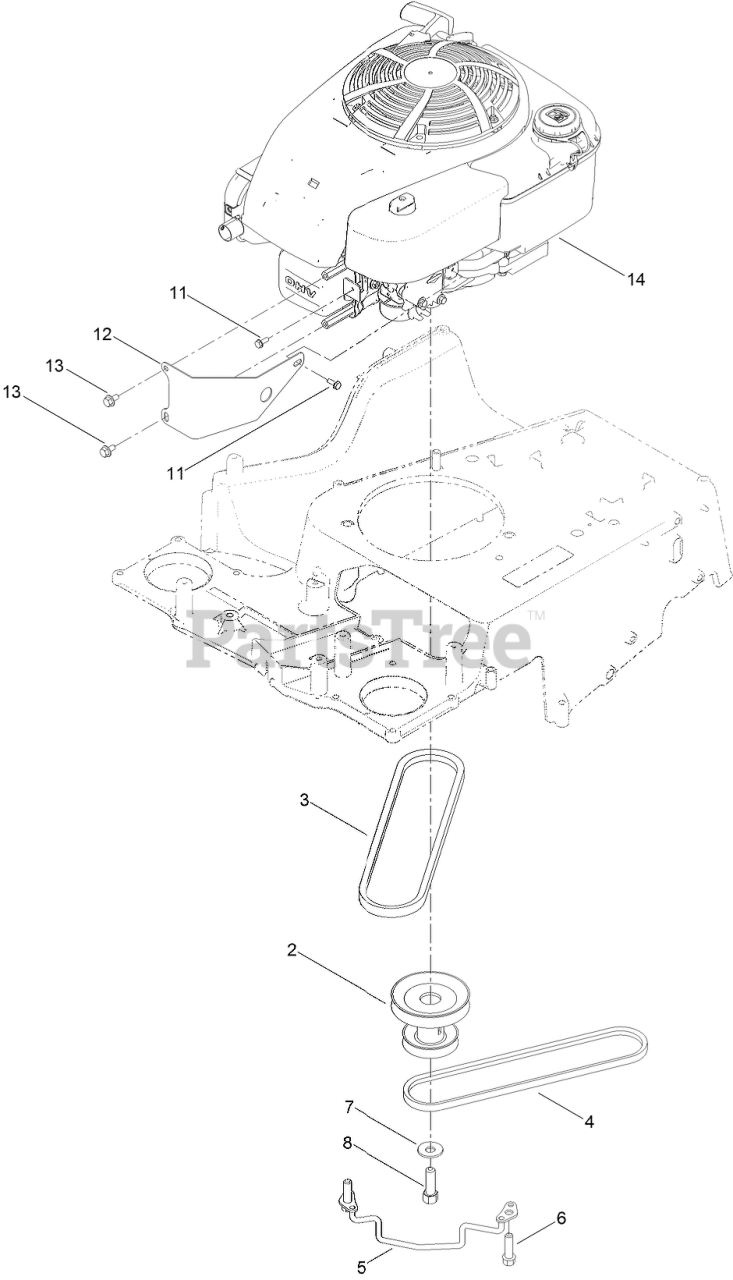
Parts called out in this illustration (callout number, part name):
2	PULLEY-ENGINE
3	V-BELT
4	V-BELT, TRACTION
6	SCREW-TAPTITE
7	WASHER-BELLEVILLE
8	SCREW-HH
11	SCREW-TAPTITE
12	GUARD-ENGINE
13	SCREW-HHF
